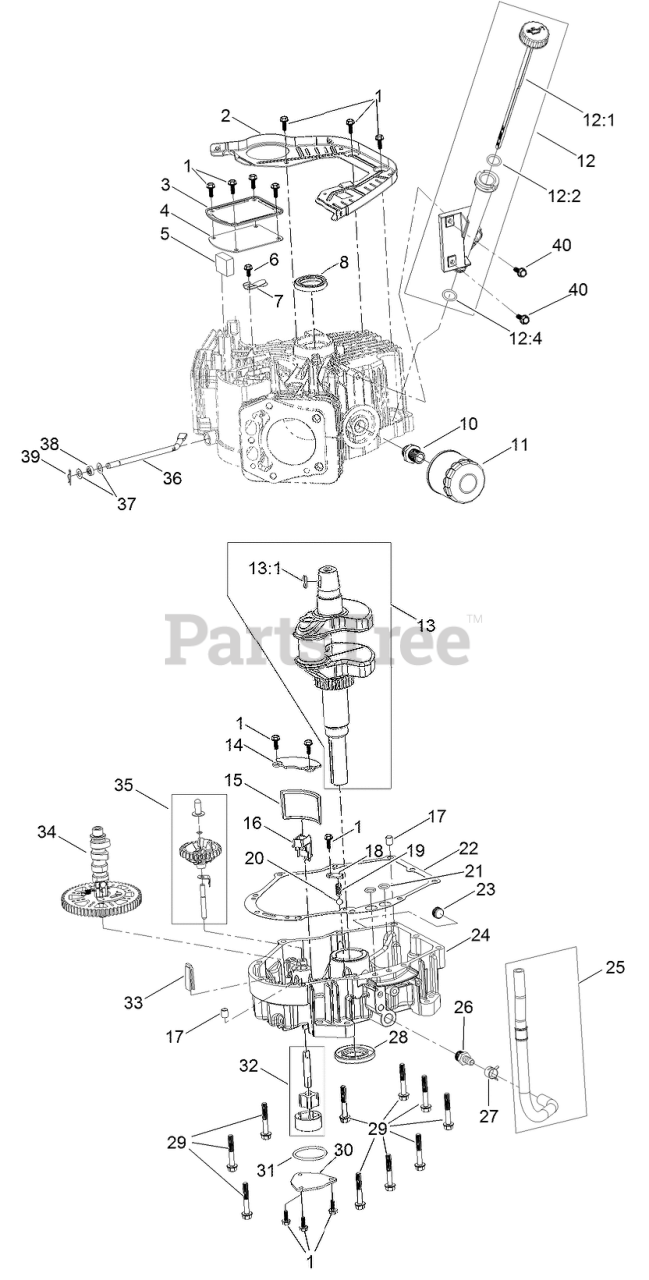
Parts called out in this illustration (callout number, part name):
1	SCREW-HHF
2	BAFFLE
3	COVER-BREATHER
4	GASKET-BREATHER
5	FILTER-BREATHER
6	SCREW-HHF
7	VALVE-BREATHER
8	SEAL-OIL
10	ADAPTOR-FILTER, OIL
12	OIL TUBE ASM
12:1	DIPSTICK
12:2	O-RING
12:4	O-RING
13	CRANKSHAFT
13:1	KEY-WOODRUFF
14	COVER-SCREEN, OIL
15	SCREEN-OIL
16	RETAINER-SCREEN
17	PIN-DOWEL
18	PLATE-RETAINER
19	SPRING
20	VALVE-BALL
21	O-RING
22	GASKET-COVER, CRANKCASE
23	PLUG-DRAIN
24	COVER-CRANKCASE
25	OIL DRAIN HOSE ASM
26	FITTING-HOSE
27	CLAMP-HOSE
29	SCREW-HHF
30	COVER-OIL PUMP
31	O-RING
32	OIL PUMP ASM
33	DEFLECTOR-OIL, RUBBER
34	CAMSHAFT
35	GOVERNOR ASM
36	SHAFT-GOVERNOR
37	WASHER-PLAIN
38	SEAL-OIL
39	PIN-HAIR
40	SCREW-HHF
